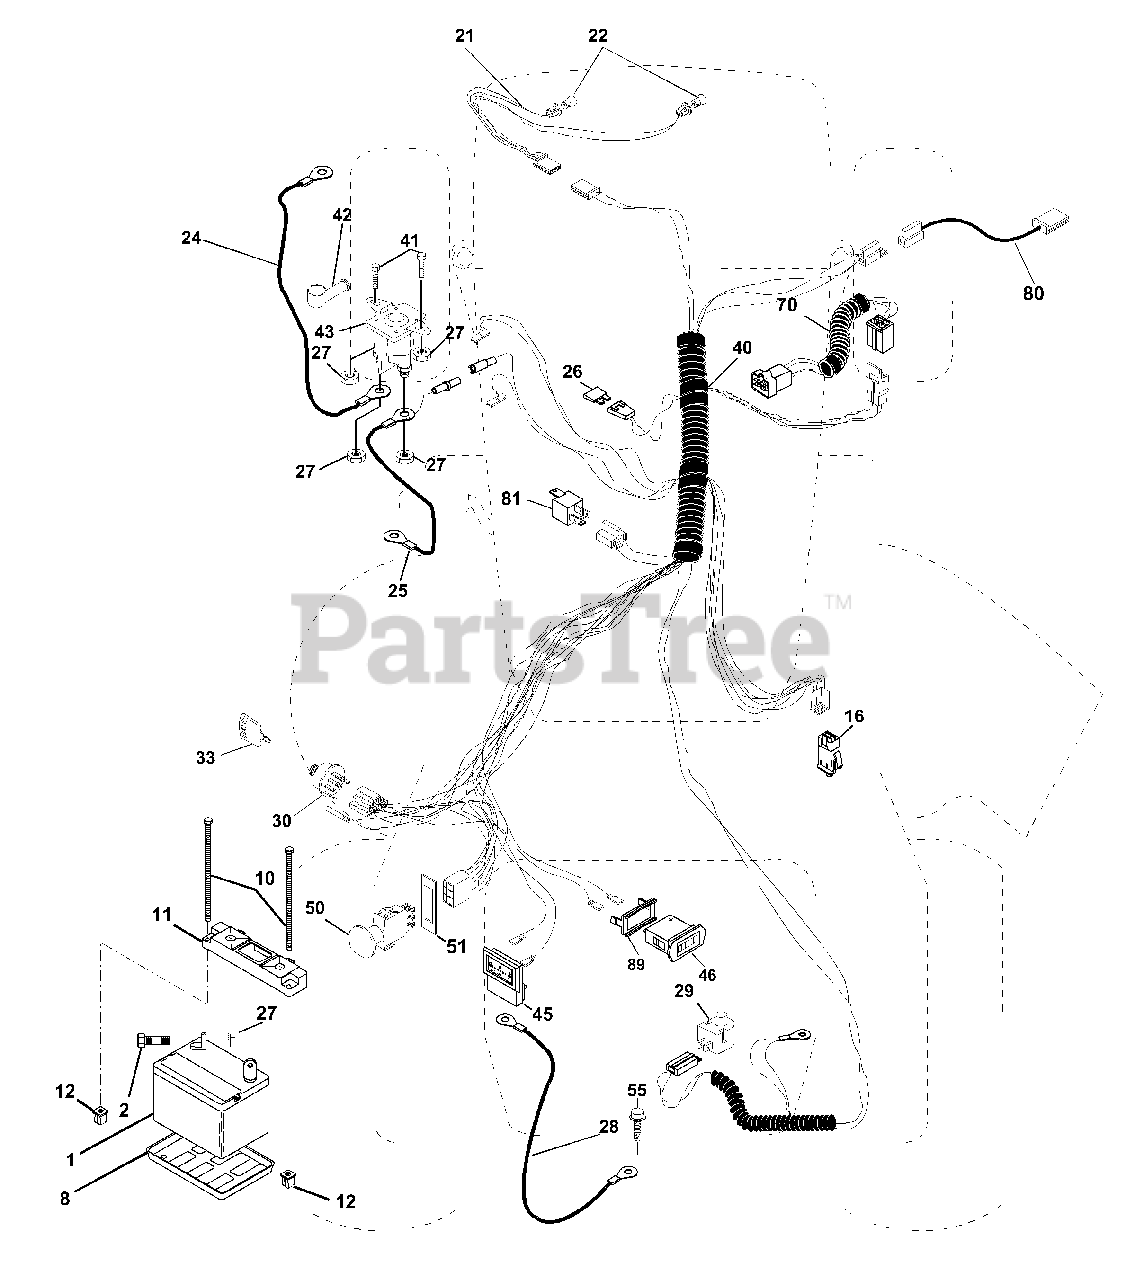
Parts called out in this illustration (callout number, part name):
1	Battery, 12 Volt, 35 Amp
2	Bolt, Hex Head 1/4-20 UNC x 3/4
8	Tray, Battery
10	Bolt, Battery Front 1/4-20 x 7.5 Zinc
11	Holddown Battery Dash Mount
12	Nut, Push Nylon 1/4" Battery Front
16	Switch Interlock Push-In
21	Harness, Light
22	Bulb, Light
24	Cable, Battery, 6 Gauge, 11", Red
25	Cable, Battery
26	Fuse, 15 Amp
27	Nut, Hex, Keps 1/4-20 UNC
28	Cable, Ground, 6 Gauge, 12", Black
29	Switch, Plunger, Normal Op Olive
30	Switch, Ignition
33	Key, Ignition
40	Harness, Ignition
41	Bolt, Hex, Fin. 1/4-20 x 1/2
42	Cover, Terminal, Red
43	Solenoid
45	Ammeter, Rectangular, 15 AMP
46	Hourmeter Snap-In
50	Switch, PTO
51	Ring, Retainer, PTO
55	Screw, Thdrol 5/16-18 x 1/2 TYT
70	Harness, Engine
80	Harness Clutch EVX
81	Relay Assembly
89	Bracket Snap-In Hourmeter
